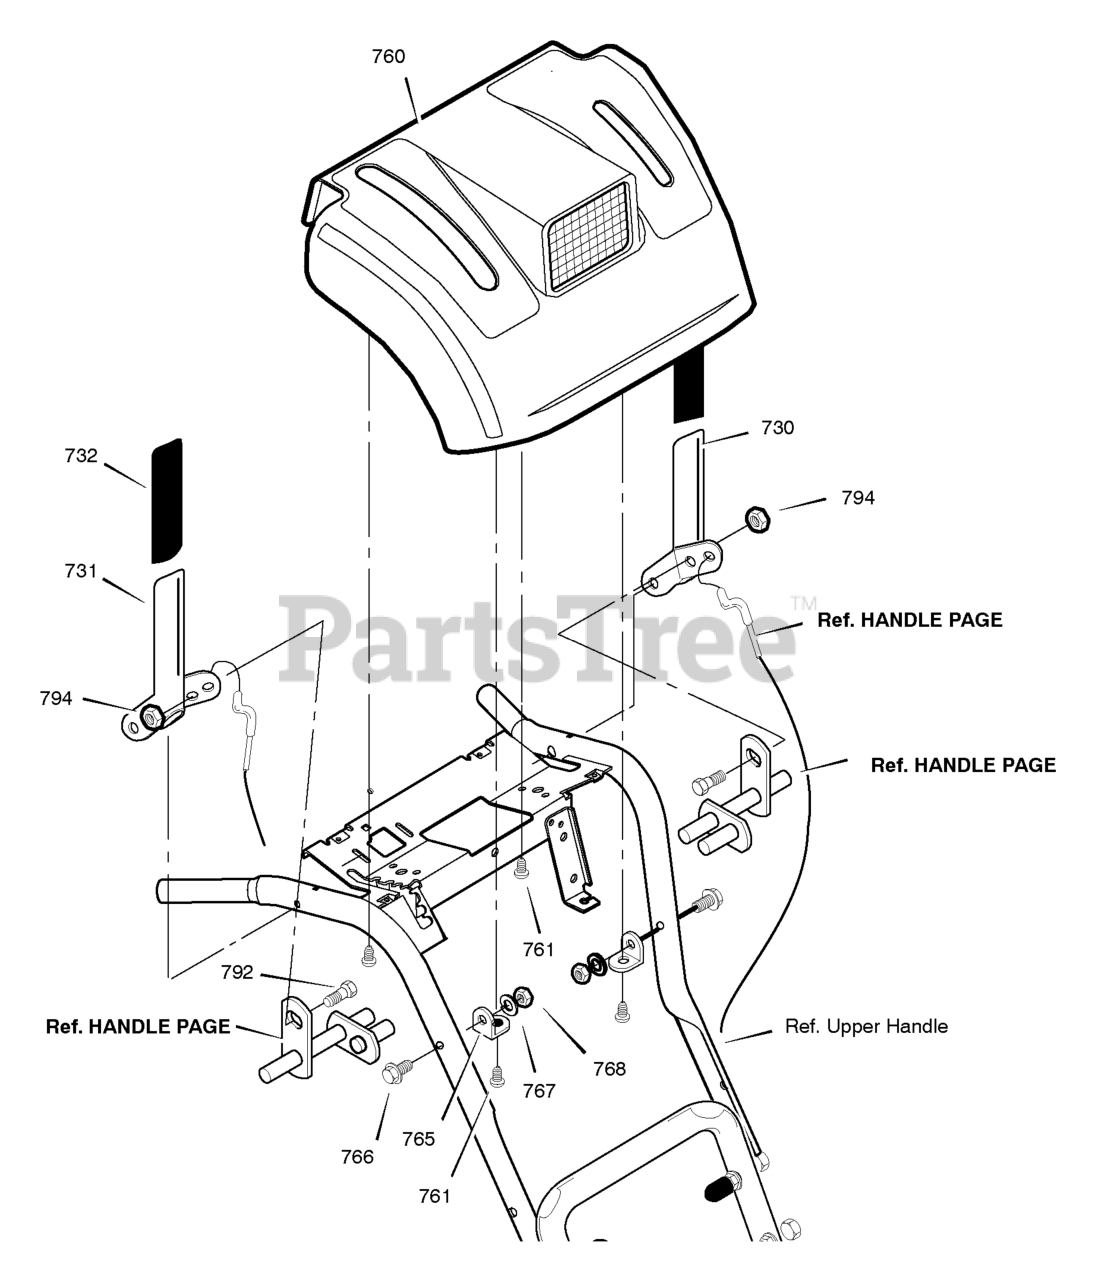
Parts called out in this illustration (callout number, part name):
730	CLUTCH HANDLE LH
731	CLUTCH HANDLE RH
732	GRIP, CLUTCH LEVER
760	PANEL, CONTROL WITH LIGHT
765	BRACKET, PANEL
766	SCREW, 5/16-18 x 1.75
767	WASHER
768	NUT, 5/16-18
792	BOLT, 1/4-20 X 0.50
794	NUT, 1/4-20
